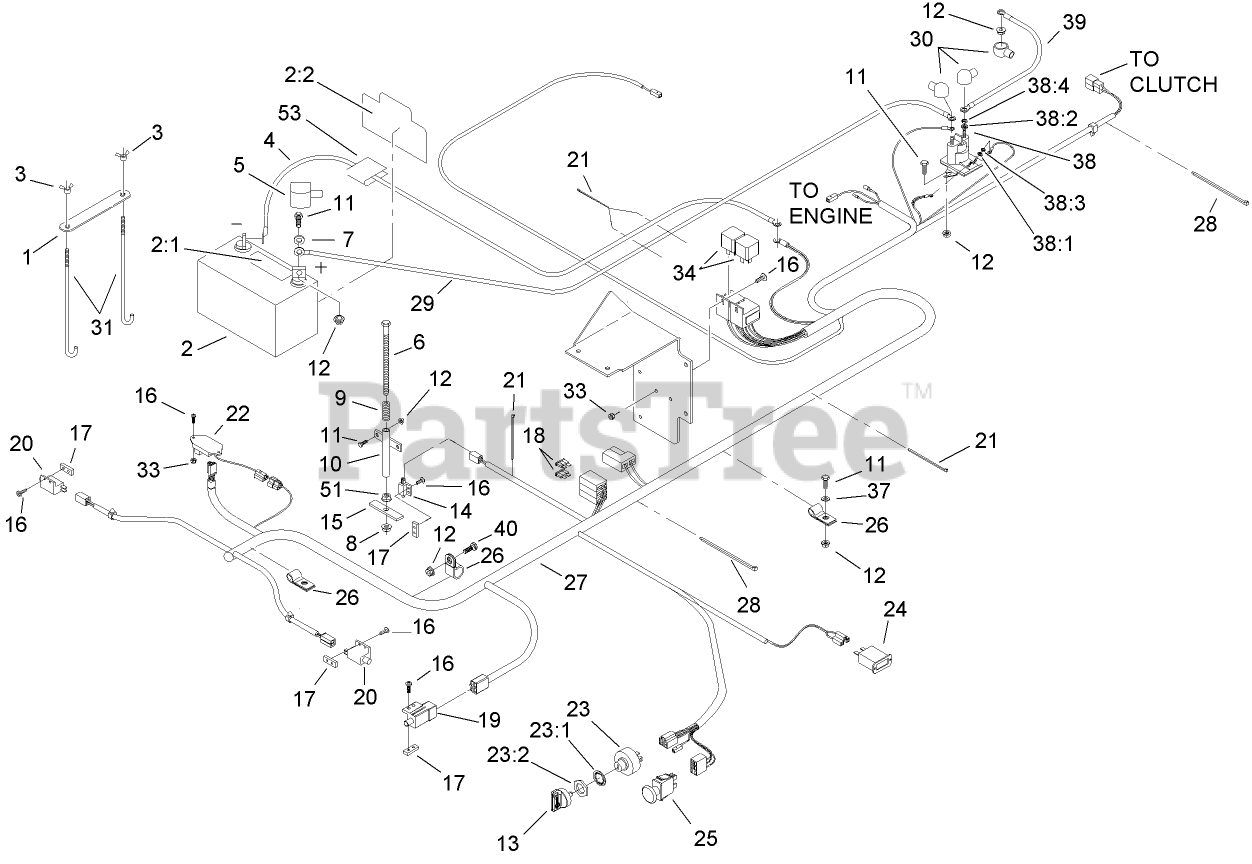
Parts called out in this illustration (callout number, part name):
1	STRAP-HOLDDOWN, BATTERY
2	BATTERY
2:1	Decal-Battery
2:2	Decal-Battery
3	WINGNUT
4	WIRE-GROUND
5	INSULATOR-BATTERY
6	SCREW-HH
7	WASHER-FLAT
8	NUT-LOCK, NI
9	SPRING-SWITCH, SEAT
10	MOUNT-SPRING, SEAT
11	SCREW-HH
12	NUT-HF
13	KEY-IGNITION
14	SWITCH-CLOSED, NORMALLY
15	PLATE-SWITCH, SEAT
16	SCREW-PPH
17	PLATE-TAPPED
18	FUSE-BLADE TYPE, 20 AMP
19	SWITCH
20	SWITCH-OPEN, NORMALLY
21	TIE-CABLE
22	MODULE-DELAY, SEAT
23	SWITCH-STARTING, KEY
23:1	WASHER-TOOTH, INTERNAL
23:2	NUT-HH
24	METER-HOUR
25	SWITCH-PTO
26	CLIP-LOOM
27	Harness-Wire
28	TIE-PLASTIC
29	WIRE-STARTER
30	INSULATOR-SOLENOID
31	BOLT-HOLDDOWN
33	NUT-LOCK, NI
37	WASHER-FLAT
38	SWITCH-SOLENOID
38:1	WASHER-LOCK
38:2	WASHER-LOCK
38:3	NUT-HEX
38:4	NUT-JAM
39	CABLE-STARTER, POSITIVE
40	SCREW-HH
51	NUT-HEX
53	DECAL-INSTRUCTIONS, CHARGING
